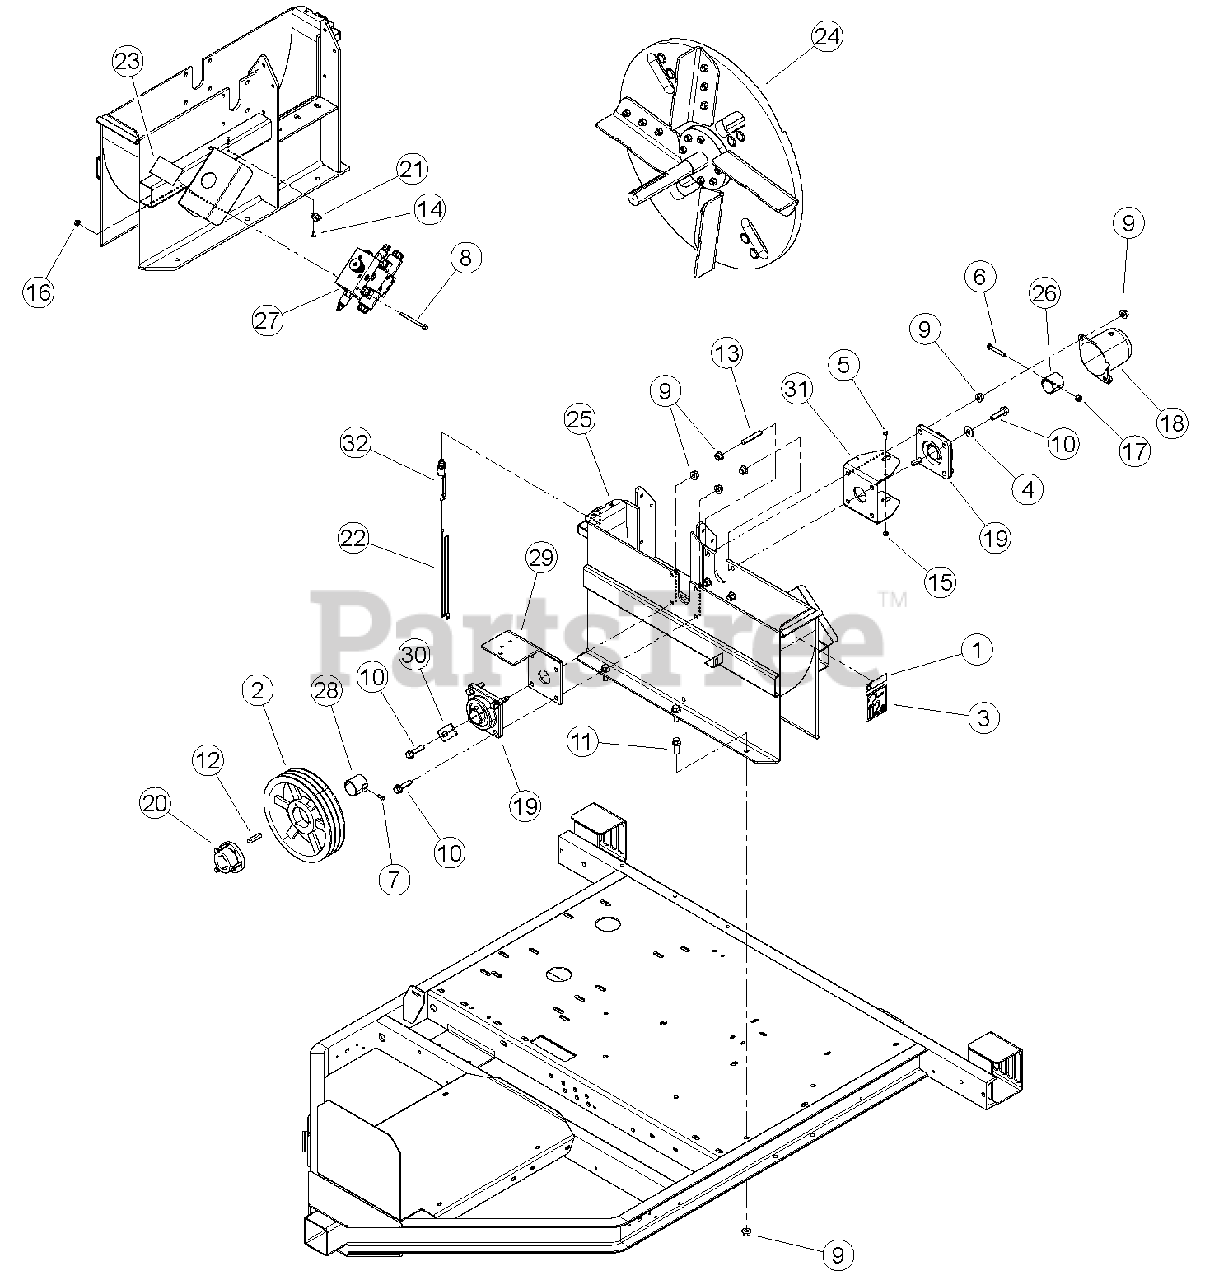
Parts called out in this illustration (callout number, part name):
1	DECAL, 72928S INFORMATION (CE COMPLIANT ONLY)
2	SHEAVE, 3BQ11.0 SK
3	DECAL, 112 DB (CE COMPLIANT ONLY)
4	WASHER, 1/2" FLAT ZP
5	BOLT, 1/4-20 X 3/4 HWH GR5 CZP
6	BOLT, 3/8 X 2-1/2 GR5 HHCS ZP
7	SCREW, 5/16-18 X 5/8 SQ HD SET
8	BOLT, 5/16 X 4 SERRATED FLANGE NC
9	NUT, 1/2-13 NYLOCK FLANGE
10	BOLT, 1/2-13 X 2 HWH GR5 CZP
11	BOLT, 1/2-13 X 1-1/2 GR5 FLANGE NC
12	KEY, 3/8" SQ X 2" LG PLAIN
13	STUD, 1/2"-13 X 3" LG B7 ZP
14	RIVET, AL BLIND 1/4 X 3/4 DOME HEAD
15	NUT, 1/4-20 NYLOCK-FLANGE
16	NUT, 5/16-18 NYLOCK-FLANGE
17	NUT, 3/8-16 NYLOCK FLANGE
18	CAP, LARGE SHAFT
19	BEARING, 1-3/4 4 BOLT FLANGE
20	BUSHING, SK 1-3/4"
21	CLAMP, CABLE MOUNT
22	DECAL, FEED SPEED
23	WIRE ASSEMBLY, 37" FM SPADE AND RING
24	ASSEMBLY, 9" CHIPPER ROTOR
25	WELDMENT, CHIPPER BOTTOM
26	COLLAR, CHIPPER LOCK
27	ASSEMBLY, HYDRAULIC FEED FLOW VALVE W/ PS
28	WELDMENT, SPACER
29	WELDMENT, GUARD SUPPORT
30	BRACKET, SENSOR SHORT MOUNT
31	BRACKET, ROTOR LOCK
32	ASSEMBLY, SEALED SWITCH
